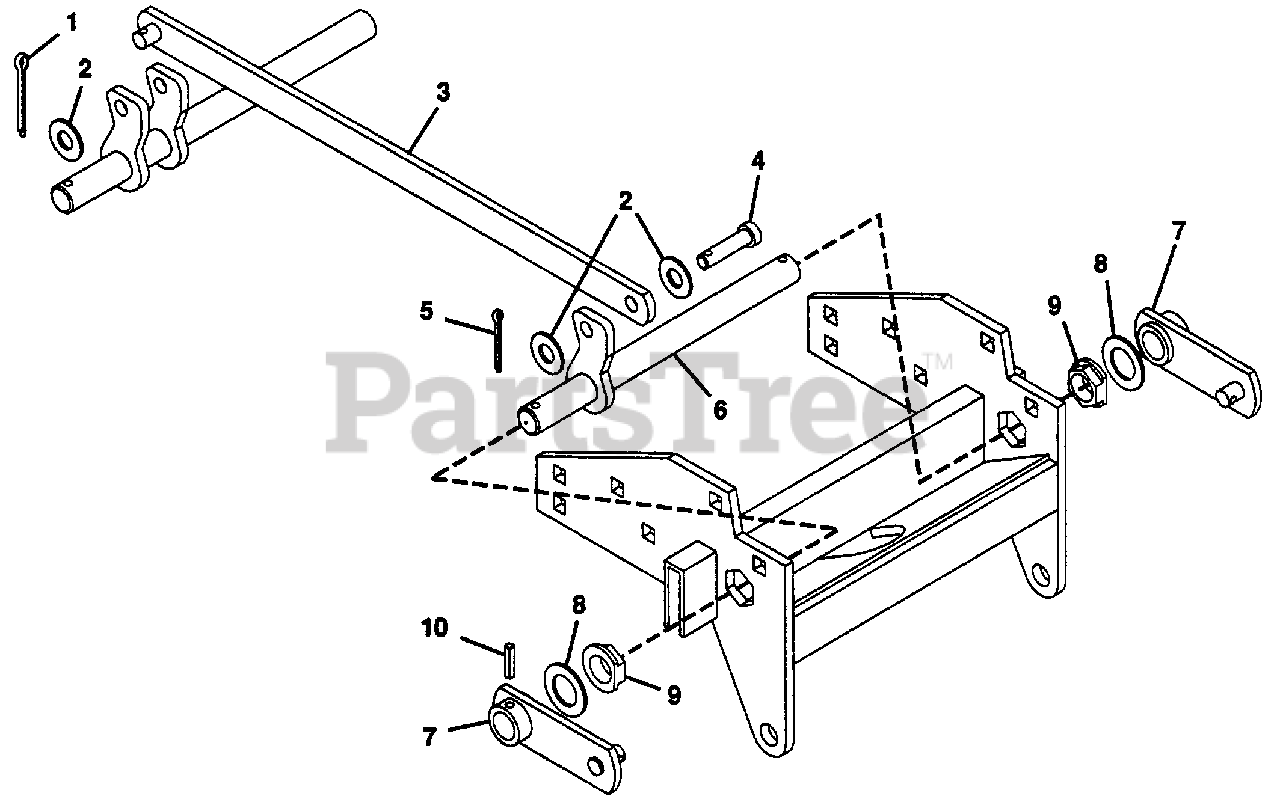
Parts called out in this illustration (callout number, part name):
1	Pin, Cotter .187x1.25
2	Washer, Flat .531x1.250x.100
3	Link, Lift
4	Pin, Clevis .50x.875
5	Pin, Cotter .125x1.00
6	Pivot, Front
7	Arm, Front Lift
8	Bearing, Thrust Race
9	Bush., Flg. 1.00x1.25x.375 Stl.
10	Pin, Spring .250x1.50
